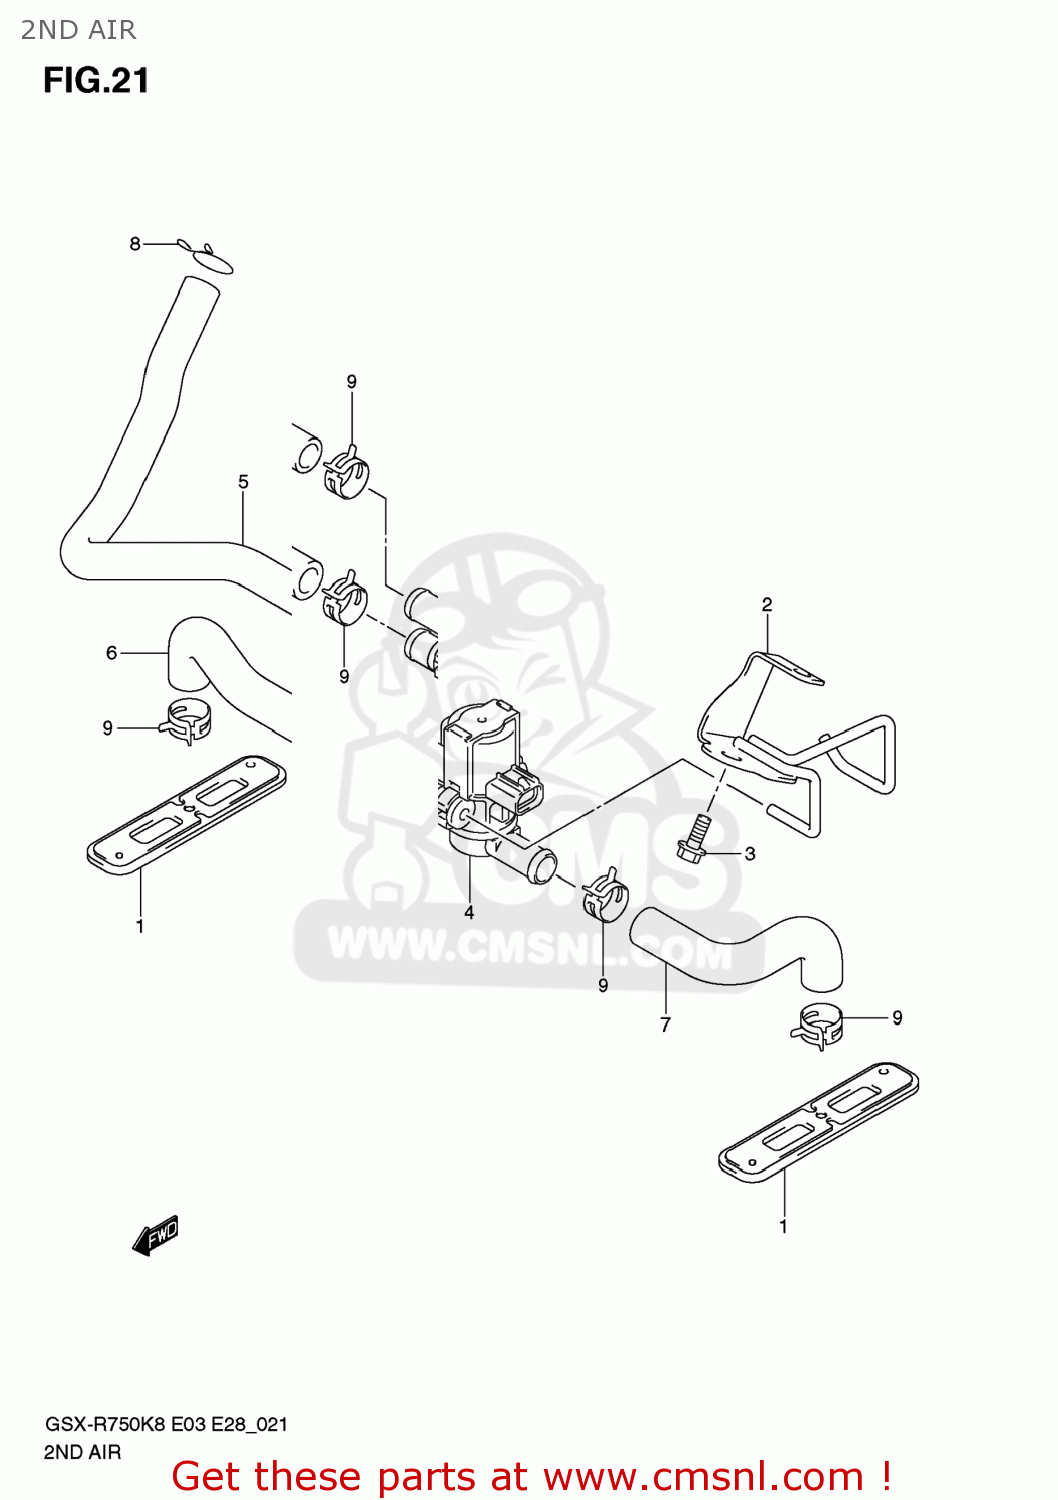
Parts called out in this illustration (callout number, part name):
1	VALVE ASSY,2ND AIR REED
2	BRACKET,2ND AIR VALVE
3	BOLT
4	VALVE ASSY,AIR CUT
5	HOSE,2ND AIR CLEANER
6	HOSE,2ND AIR VALVE,R
7	HOSE,2ND AIR VALVE,L
8	CLIP
9	CLIP
